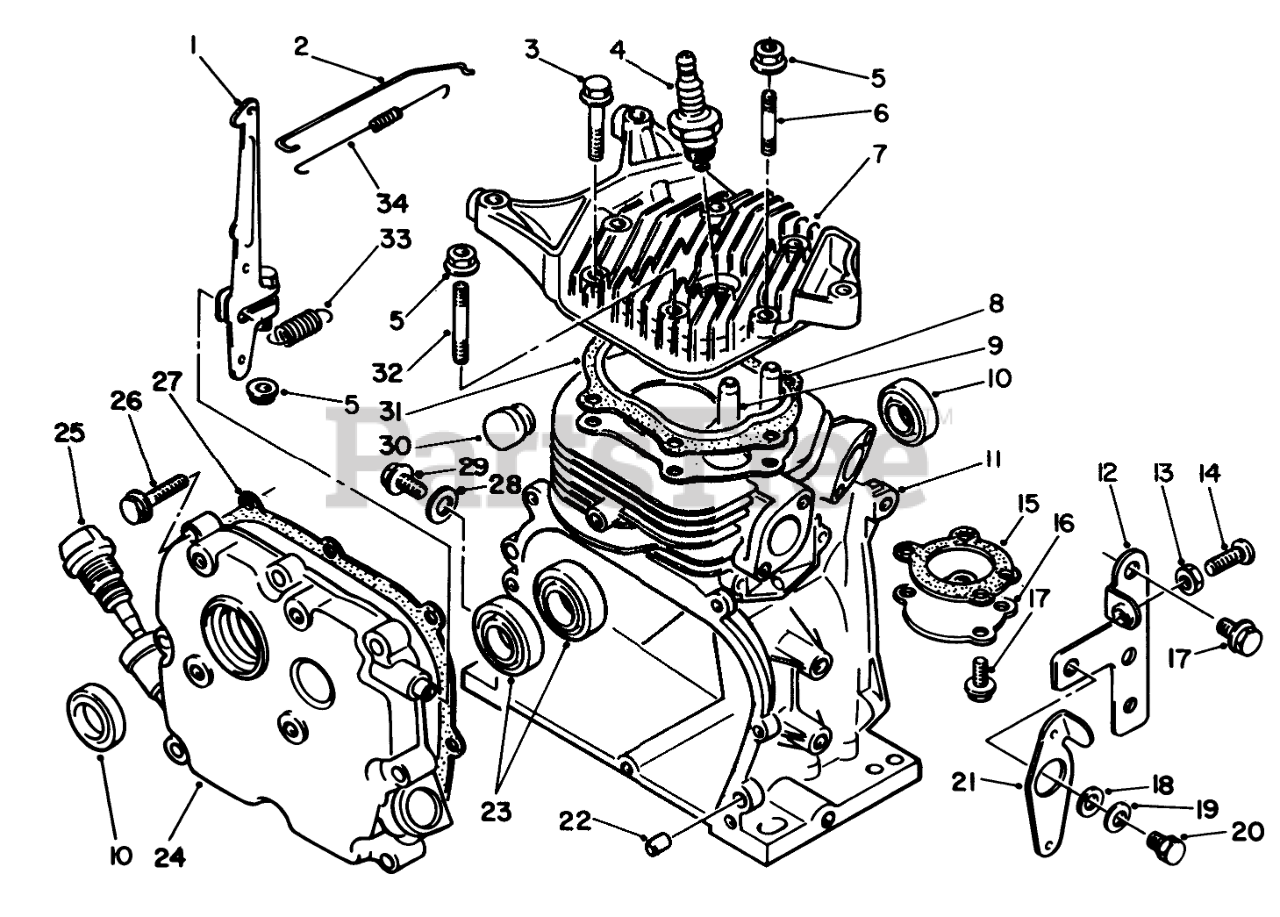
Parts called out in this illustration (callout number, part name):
1	Lever-Throttle Conlrol
2	Rod-Carburetor
4	Spark Plug
6	Bolt-Stud
7	Cylinder Head
8	Guide-Intake Valve
9	Guide-Exhaust Valve
10	OIL SEAL
11	Cylinder Assembly
12	Bracket-Governor Control
13	Nut-Jam
14	Screw-Round Phillips Hd.
15	GASKET
16	Cover-Level Sensor
18	WASHER-THROTTLE
19	Washer
21	Lever
23	Bearing
24	Cover-Crankcase Side
25	Gauge-Oil Level
27	CRANKCASE GASKET
28	Gasket
29	Bolt
31	CYL. GASKET
32	Bolt-Stud
33	SPRING
34	SPRING
